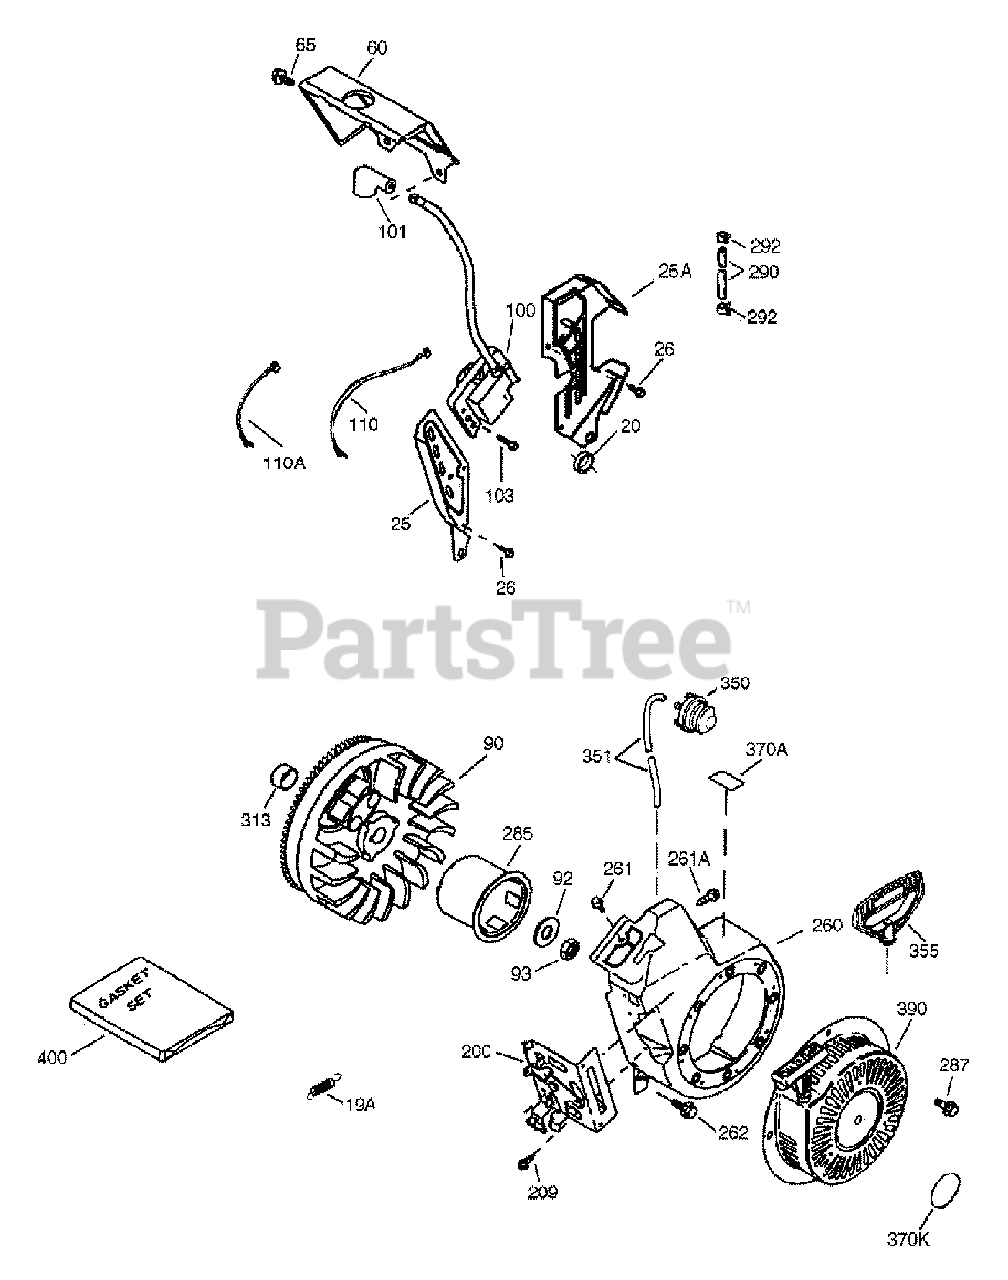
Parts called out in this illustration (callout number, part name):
19A	Governor Spring
25	Air Baffle (Left)
25A	Air Baffle (Right)
26	Screw, 10-24 x 9/16"
60	Blower Housing Extension
65	Screw, 10-24 x 9/16"
92	Belleville Washer
93	Flywheel Nut
100	Solid State Ignition
101	Spark Plug Cover
103	Screw, T-15, 10-24 x 15/16"
110	Ground Wire
110A	Ground Wire
200	Control Bracket
209	Screw, 10-32 x 1/2"
260	Blower Housing
261	Screw, 1/4-20 x 31/64"
261A	Screw, 10-32 x 1/2"
262	Screw, 1/4-20 x 31/64"
285	Starter Cup
287	Screw, 1/4-20 x 31/64"
290	Fuel Line
292	Fuel Line Clamp
350	Primer Assembly
351	Primer Line
355	Starter Handle (Mitten Grip)
370A	Lubrication Decal
370K	Starter Decal
390	Rewind Starter
400	Gasket Set
